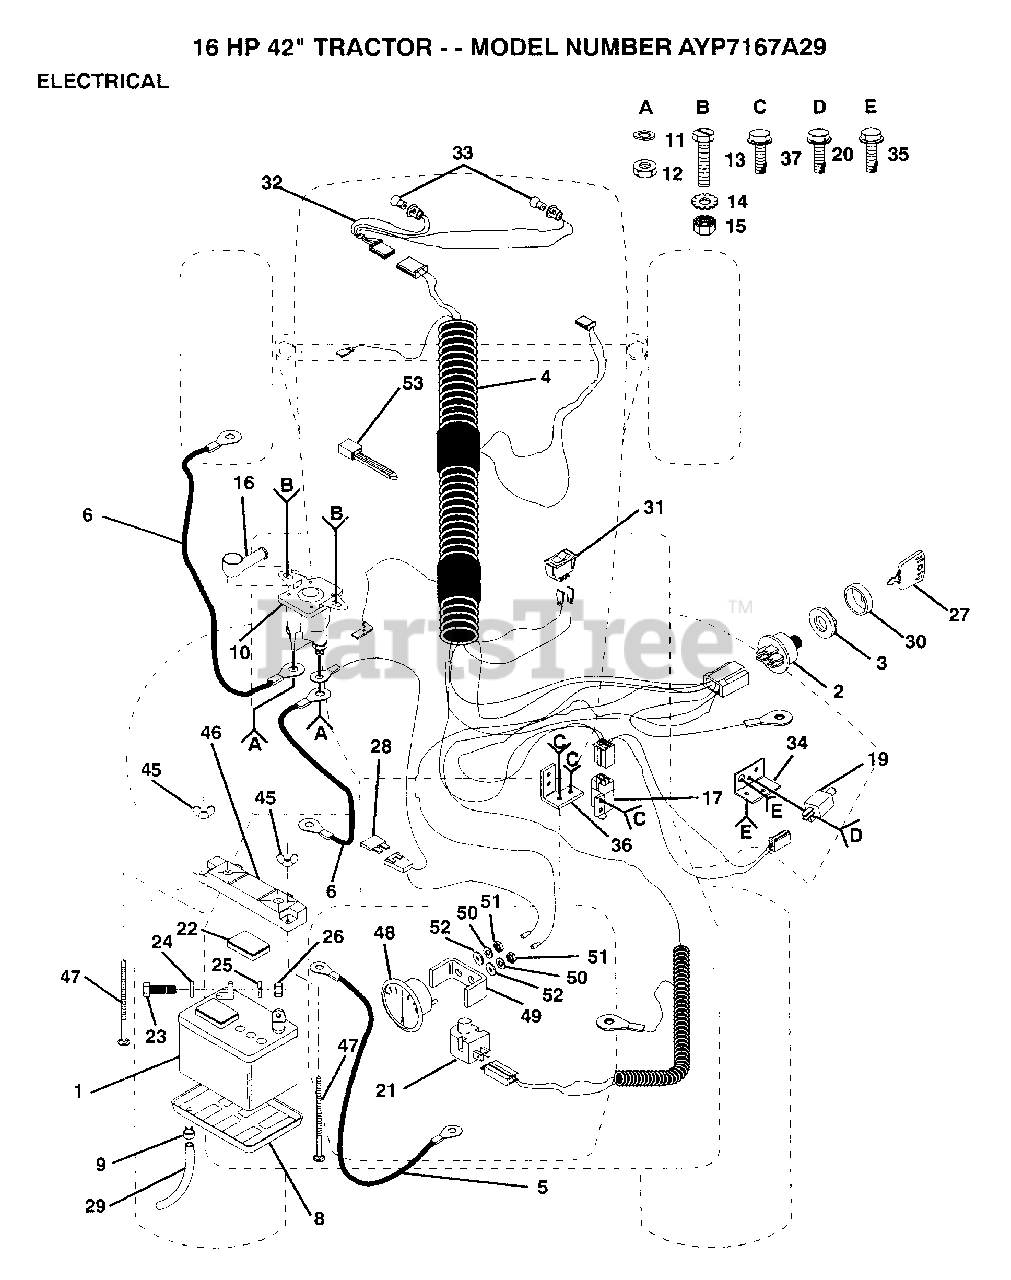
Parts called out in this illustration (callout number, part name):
3	NUT IGNITION
4	IGNITION HARNESS
5	CABLE T
6	CABLE-BATTERY T
7	"CABLE T, BATTERY"
8	"TRAY T, BATTERY"
9	HOSE CLAMP T
12	NUT
13	BOLT
15	NUT
17	SWITCH INTERLOCKT
19	SWITCH-INTER. GT
20	SCREW
21	SWITCH SEAT
22	"CAP,BATTERY "
23	BOLT LT
24	WASHER
25	LOCKWASHER
27	KEY
28	FUSE HYT
31	SWITCH LT
34	BRACKET LT
35	SCREW
36	SWITCH BRACKET
37	SCREW
47	BOLT
48	AMMETER T
52	WASHER
53	WIRE TIE
